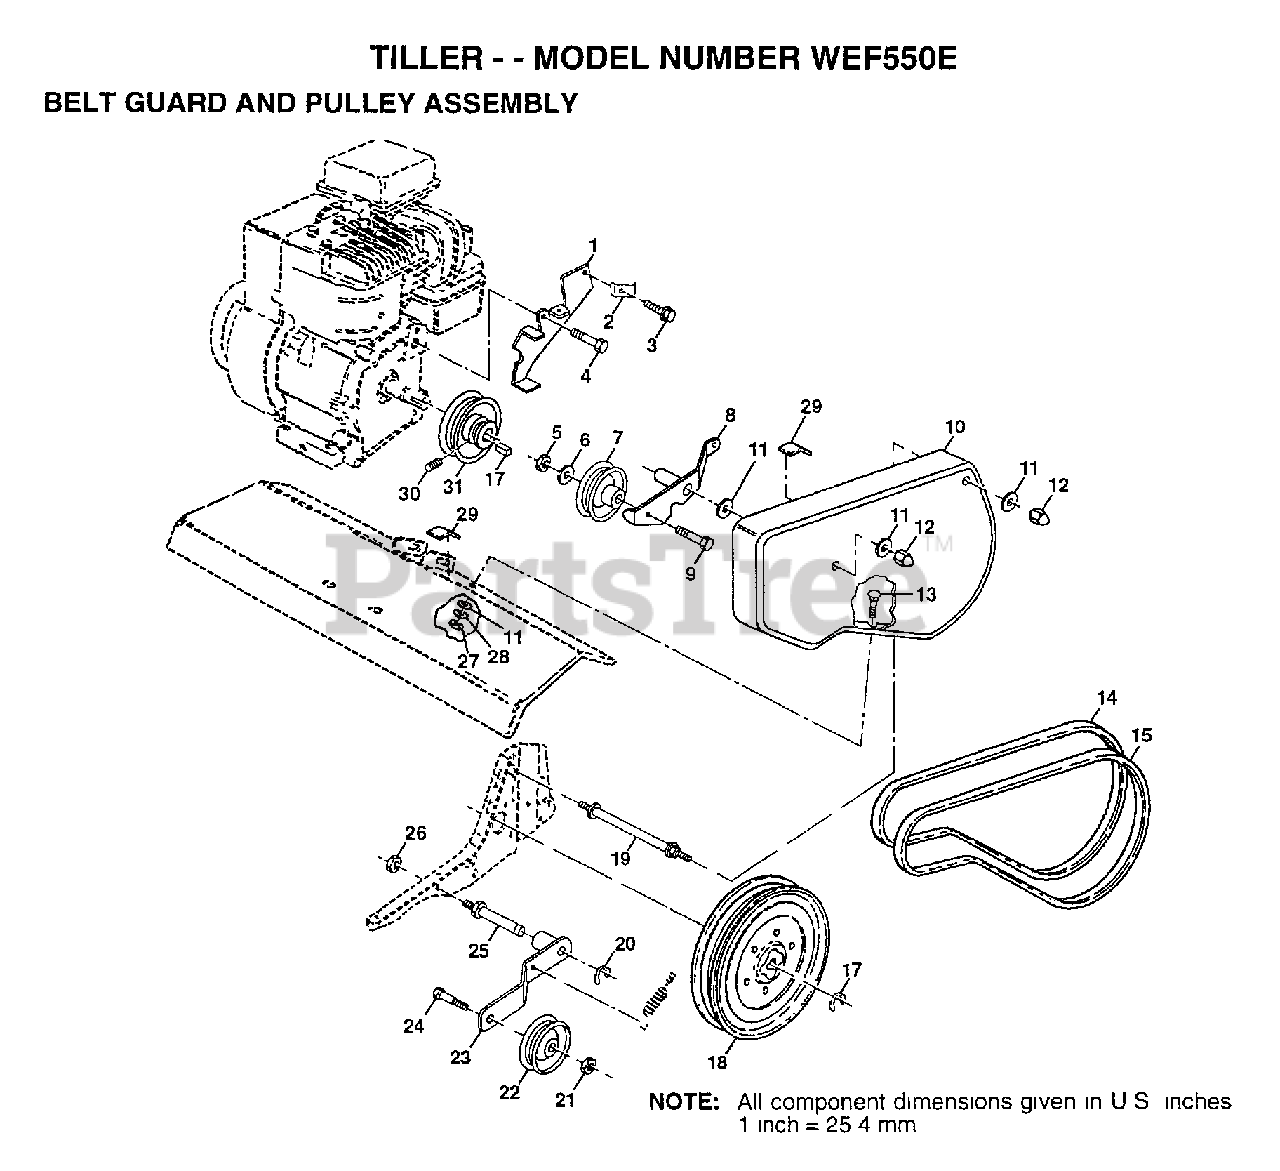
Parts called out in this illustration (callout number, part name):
2	CONDIUT CLIP T
5	NUT.HEX.3/8-16UNC
6	WASHER
7	PULLEY W/SPACER
8	ARM.ASM.REV.IDLER
10	GUARD BELT
11	WASHER
12	NUT-CAP TI
13	BOLT T
14	BELT-V
16	SET SCREW
17	KEY T
19	BOLT TI
20	KLIP RING TI
21	NUT
23	IDLER ARM TI
25	SHAFT IDLER TI
26	JAM NUT TI
28	LOCKWASHER
29	PAD IDLER TI
30	SET SCREW
31	ENGINE PULLEY TI
